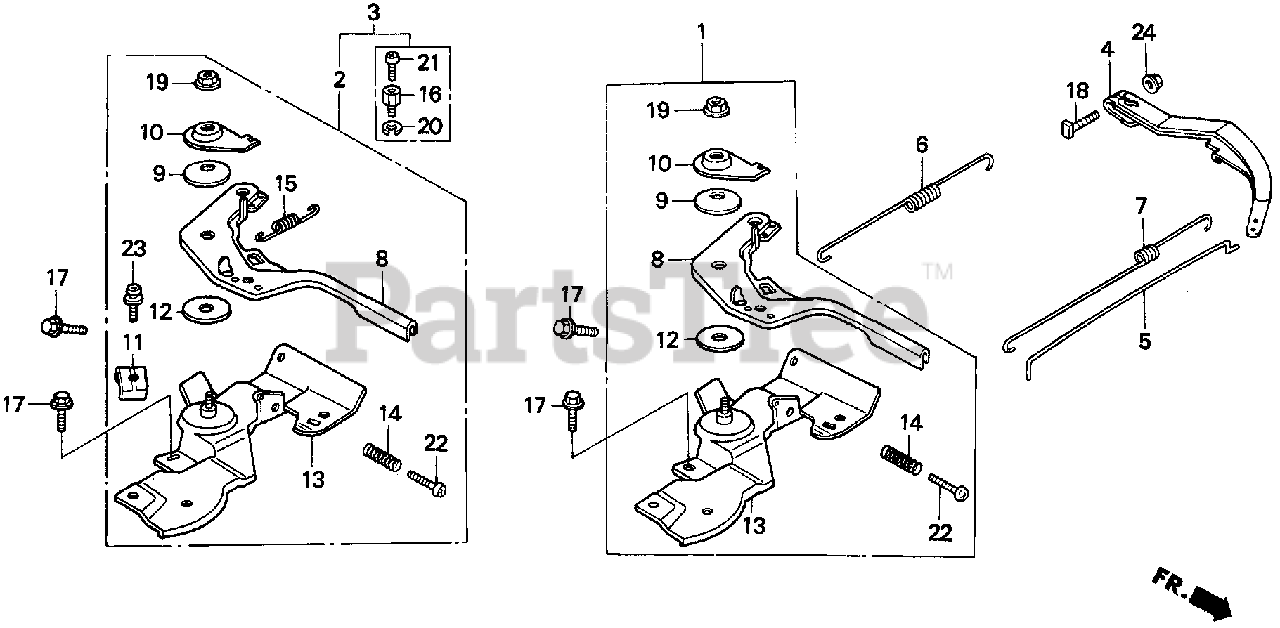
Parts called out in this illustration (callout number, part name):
2	CONTROL ASSY. (REMOTE)
4	ARM, GOVERNOR
5	ROD, GOVERNOR
6	SPRING, GOVERNOR
7	SPRING, THROTTLE RETURN
8	LEVER, CONTROL
9	SPRING, LEVER
10	WASHER, CONTROL LEVER
11	HOLDER, CABLE
12	SPACER, CONTROL LEVER
13	BASE, CONTROL
13	BASE, CONTROL (REMOTE)
14	SPRING, CONTROL ADJUSTING
15	SPRING, CABLE RETURN
17	BOLT, FLANGE (6X12) (CT200)
18	BOLT, GOVERNOR ARM
19	NUT, SELF-LOCK (6MM)
22	SCREW, PAN (5X25)
23	SCREW-WASHER (5X16)
24	NUT, FLANGE (6MM)
